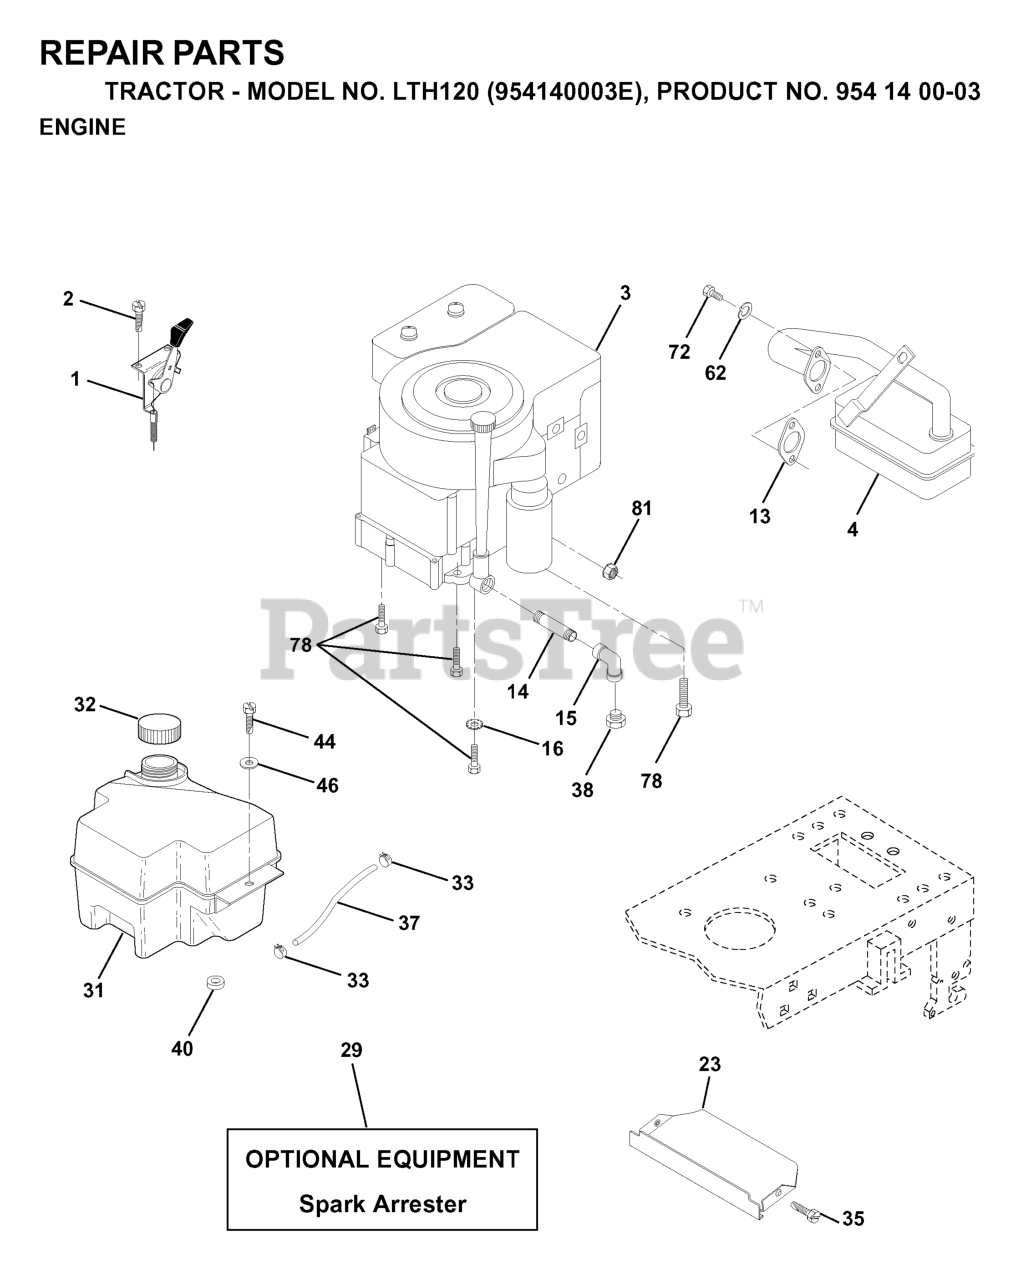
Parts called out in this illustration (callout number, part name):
1	HANDLE HALF (L)
3	SHAFT PIVOT
4	LEVER STOP
9	SPRING RUBBER
12	CONTACT SPRING
13	CONTACT SPRING
14	TRIGGER 848L5W34C0
16	HANDLE HALF (R)
17	SCREW
19	SQUARE NUT M5
20	HOLDER, HANDLE
21	HANDLE HOLDER
22	KNOB
25	WIRING ASSY
26	CORD COMPLETE
27	CABLE, COMP
28	ASSY LEVER SET
